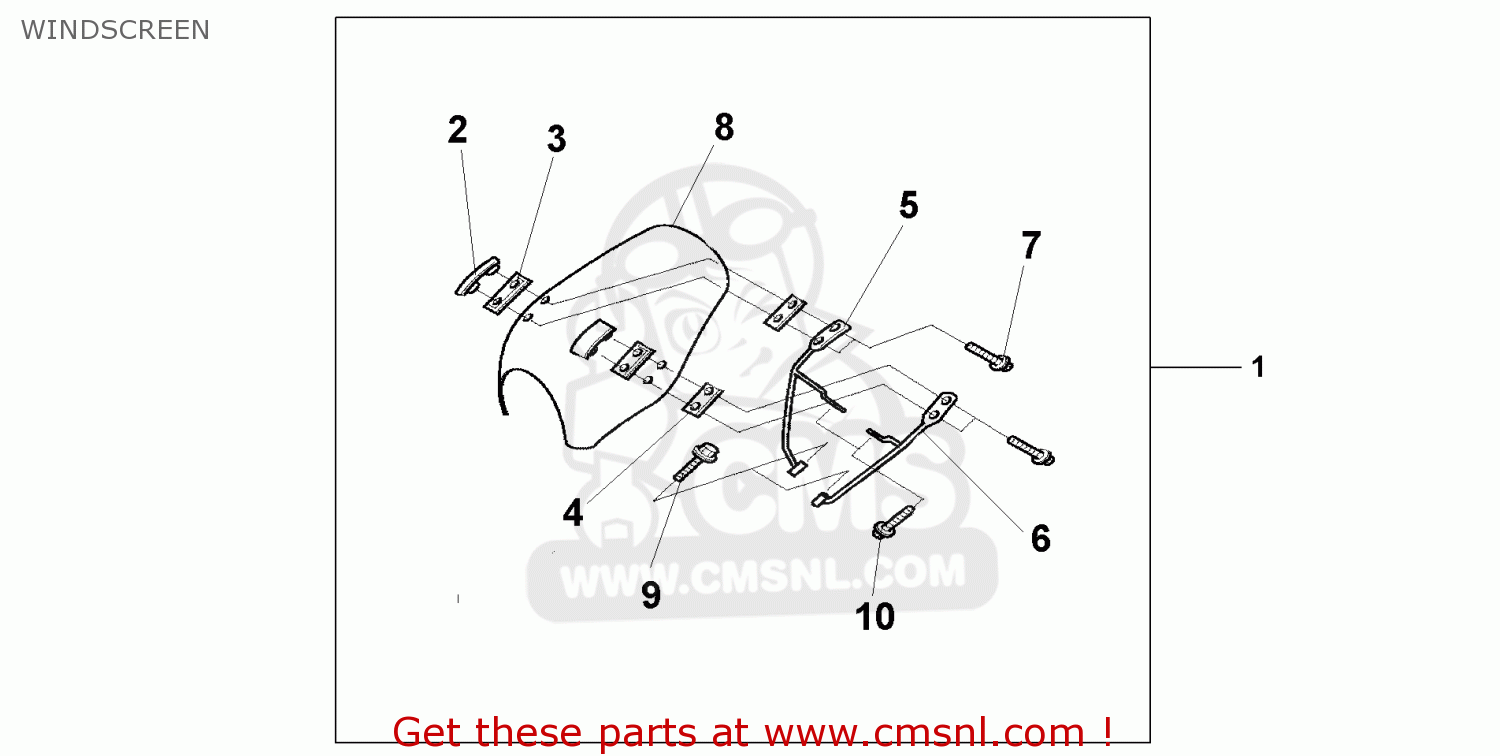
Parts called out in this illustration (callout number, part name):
1	WINDSCREEN
2	BRACKET, WINDSHIELD
3	RUBBER OUTER
4	RUBBER INNER
5	WINDSHIELD STAY R
6	WINDSHIELD STAY L
7	BOLT,FLANGE,6X10
8	WINDSHIELD
9	BOLT,FLANGE 6X30
10	BOLT FLANGE 8X20
